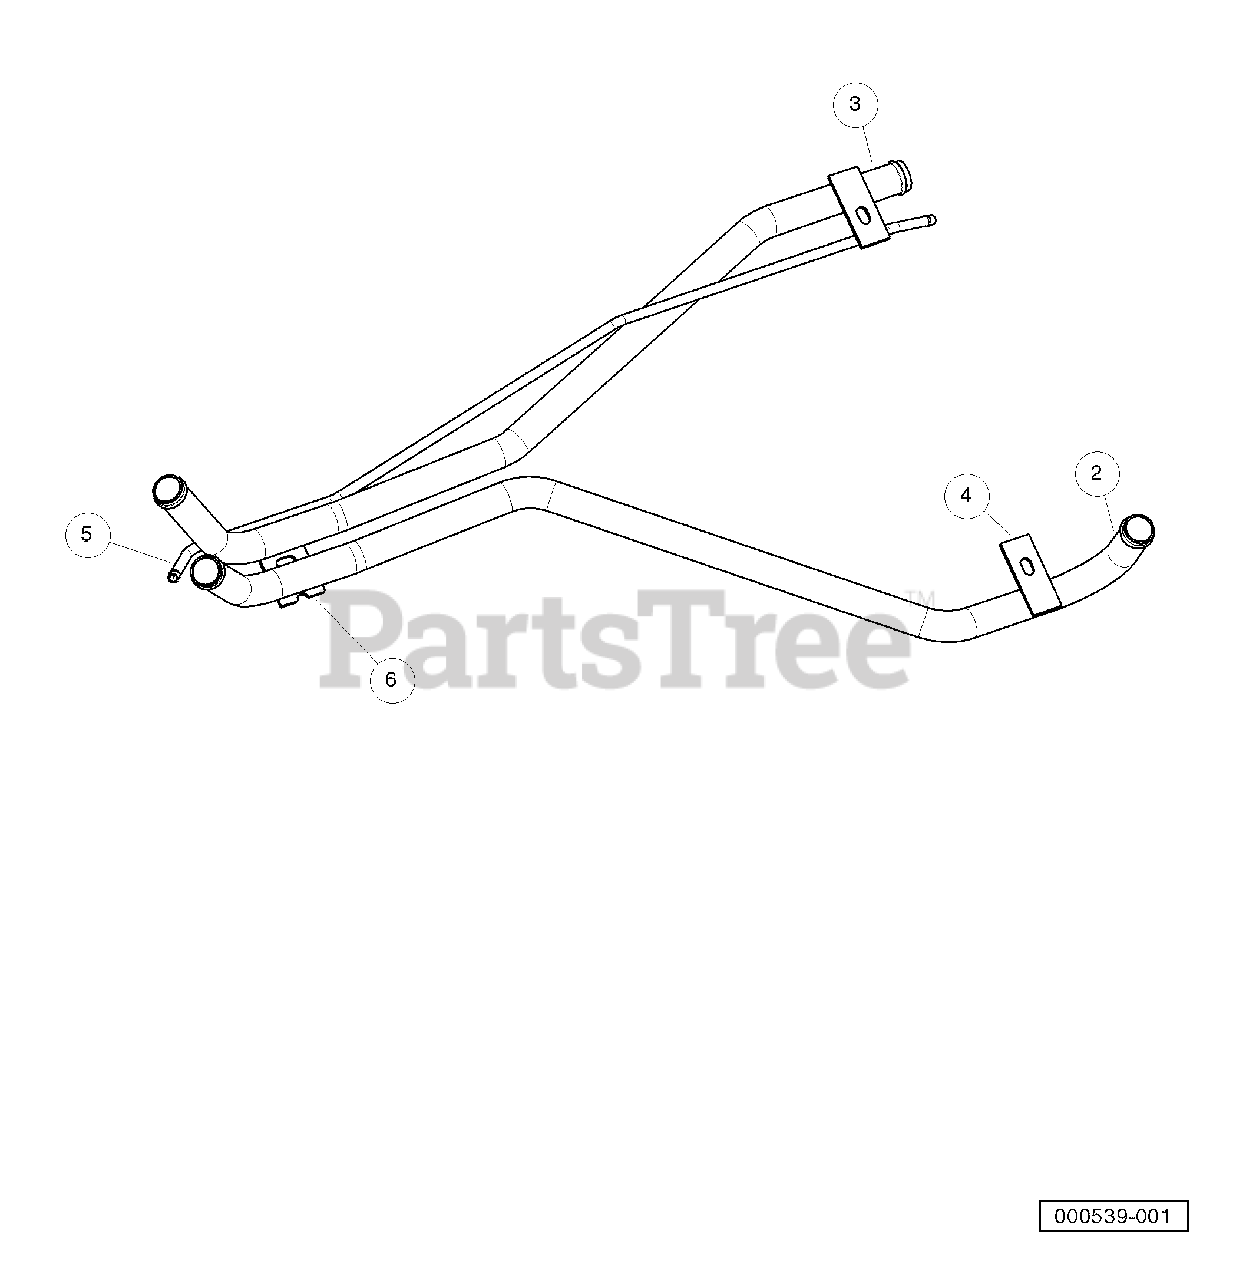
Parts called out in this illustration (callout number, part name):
1	Weldment, Group, Coolant Pipe
2	Pipe, Coolant Upper
3	Pipe, Coolant Lower
4	Tab, Rear Mntg, Coolant Pipe
5	Pipe, Vent, Coolant
6	Tab, Cooling Pipe Mount
